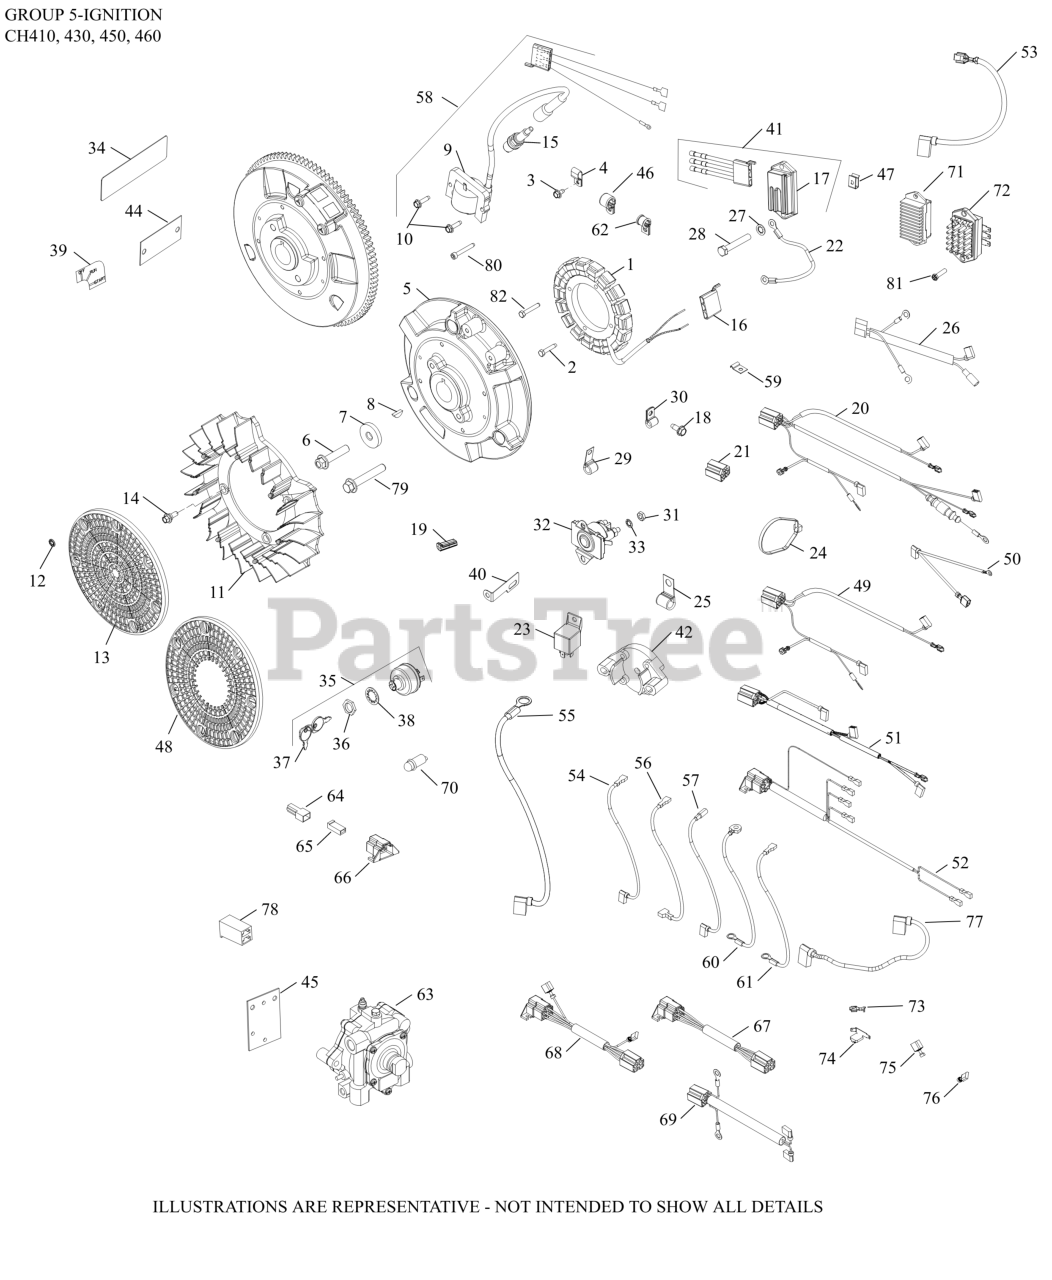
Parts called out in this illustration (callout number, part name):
1	KIT, 15 / 20 AMP STATOR
2	SCREW, M5X0.8X25 - (#25086402S)
3	SCREW, FLG THD FRM M5X.8X10
6	SCREW, FLG M10X1.5X45-USE 25 086 361-S
7	WASHER, FLAT 13/32"
8	KEY, 3/16" X 5/8"
9	MODULE, IGNITION
10	SCREW, FLG THD FRM M5X.8X20-(#25086399S)
14	BOLT, SHOULDER
15	PLUG, SPARK (STD)
16	CONNECTOR
17	REGULATOR/RECTIFIER-(#2540337S)
18	SCREW,FLG THD FRM M6X1.0X16-(#25086397S)
20	HARNESS, WIRING-DISCONTINUED
21	CONNECTOR
22	LEAD, STARTER SOLENOID-DISCONTINUED
22	LEAD, GROUND SOLENOID
29	CLIP, CABLE
30	CLIP, TUBE & WIRING (KM)
31	NUT, JAM 1/4-20 GRADE 2
32	SOLENOID - WATERPROOF (KM)-USE 25 435 08
33	WASHER, INT TOOTH LOCK 1/4"
34	DECAL, SHUTDOWN
35	KEY ASSEMBLY SWITCH-USE 25 099 37-S
36	NUT, KEY SWITCH
37	KEY, SET OF 2
38	WASHER, INTERNAL TOOTH
39	DECAL, IGNITION
40	BRACKET, GROUND STRAP
43	FLYWHEEL - USE 12 025 16-S
